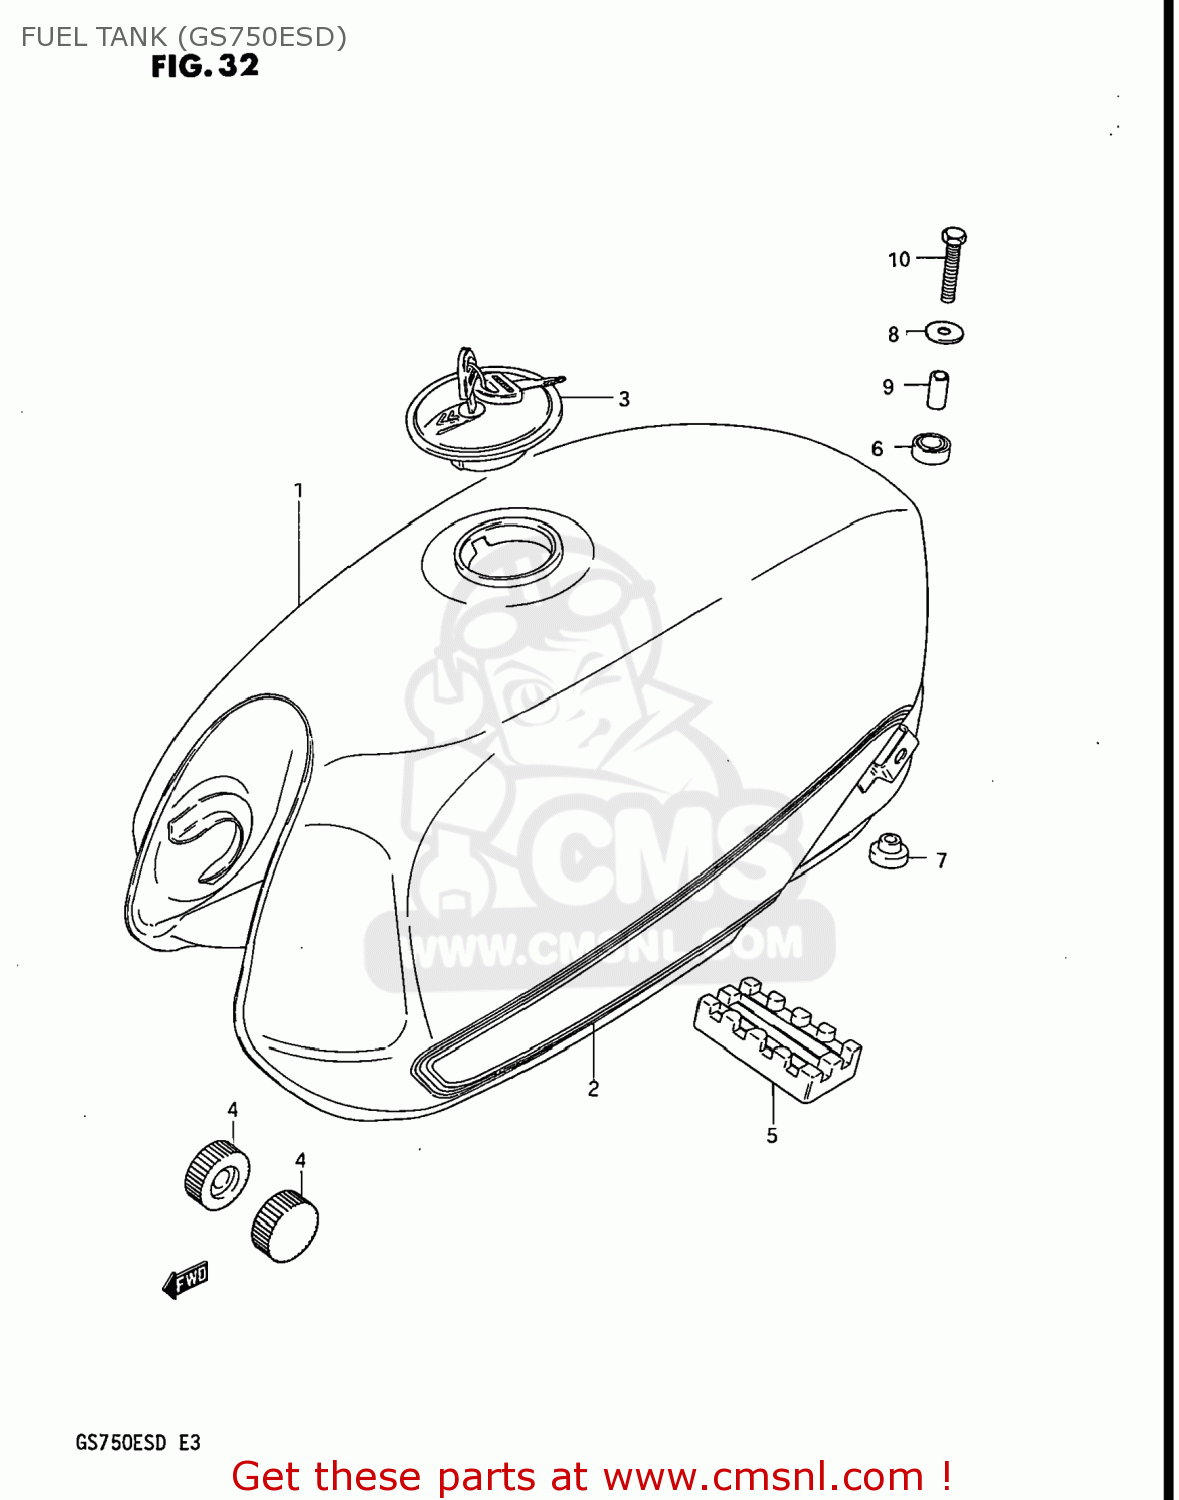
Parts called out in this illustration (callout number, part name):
1	TANK ASSEMBLY,FUEL
2	TAPE SET,FUEL TANK
3	CAP SET,FUEL TANK
4	CUSHION
5	CUSHION,FUEL TANK CTR
6	CUSHION
7	CUSHION
8	WASHER (6.5X24X1.6)
9	SPACER
10	BOLT
